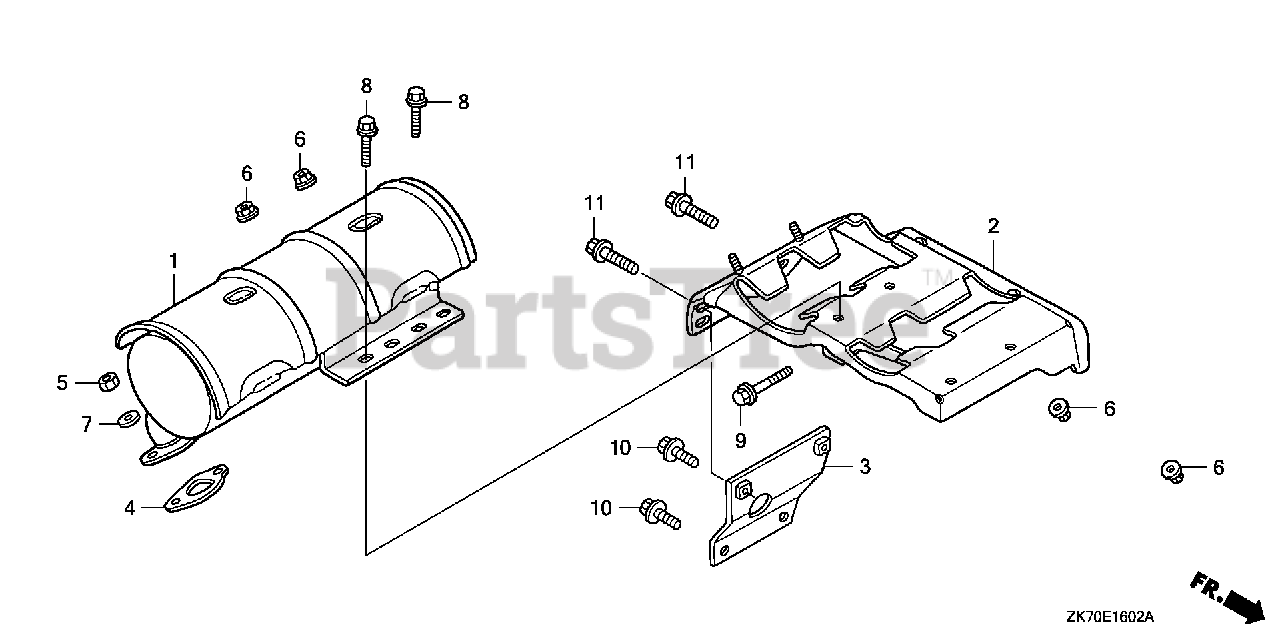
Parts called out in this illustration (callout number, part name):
2	STAY, MUFFLER
4	GASKET, MUFFLER
5	NUT, HEX. (8MM)
6	NUT, FLANGE (6MM)
8	BOLT, FLANGE (6X16)
9	BOLT, FLANGE (6X25)
11	BOLT, FLANGE (8X20)
